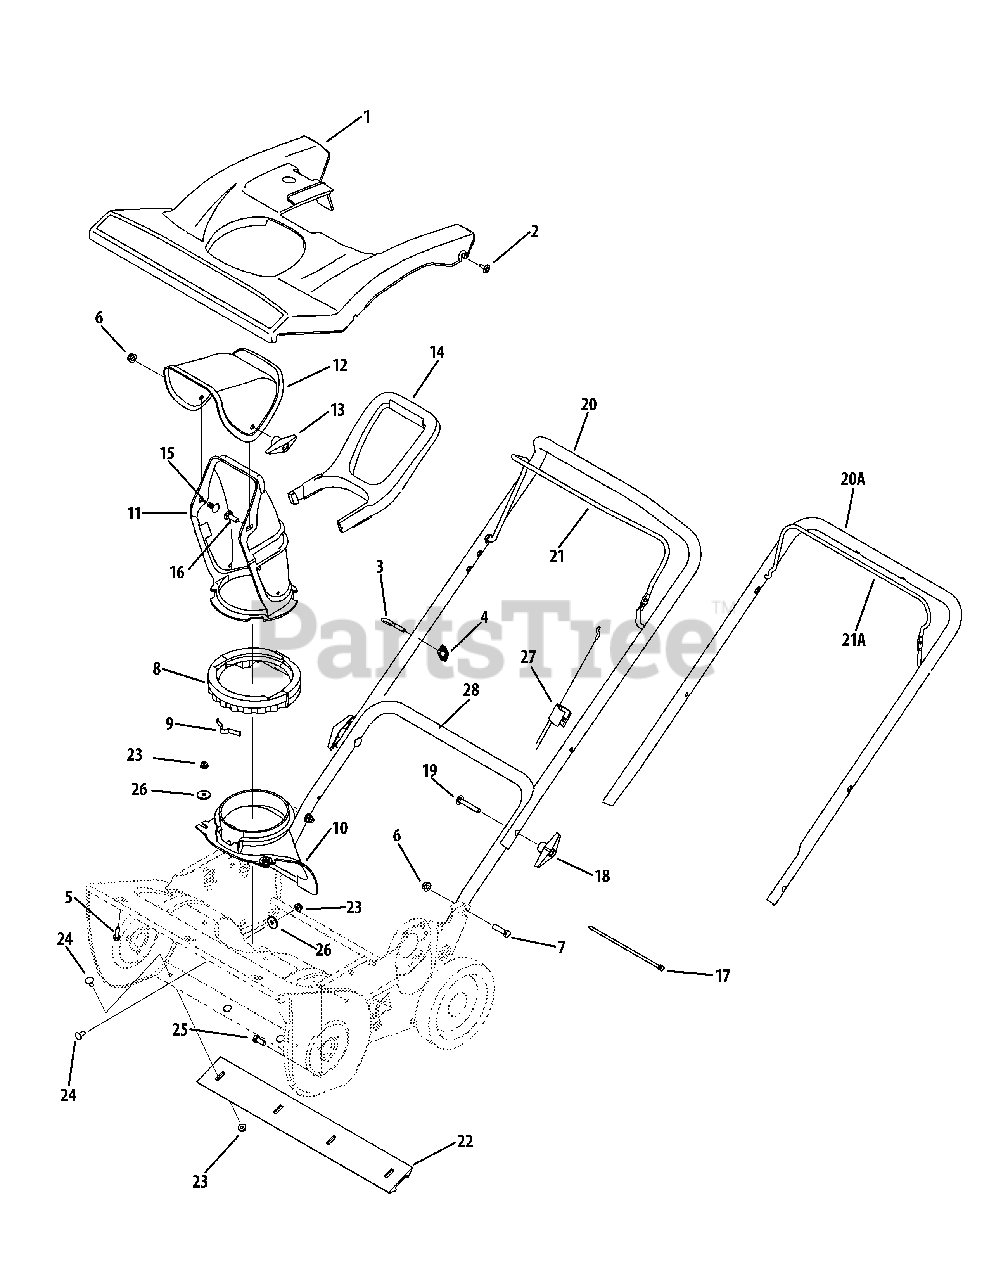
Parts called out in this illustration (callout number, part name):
1	Shroud
2	Hex Washer Screw, 10-16 x .625
3	Eye Bolt, 1.4-20
4	Knob Handle
5	Hex Washer Screw, 1.4-15 x .750
6	Flange Lock Nut, 5.16-18
7	Hex Screw, 5.16-18 x 1.25
8	Lower Chute Ring
9	Chute Adjustment Spring
10	Chute Adapter
11	Lower Chute, 5h Diameter
12	Upper Chute
13	Wing Knob
14	Chute Handle
15	Carriage Bolt, 5.16-18 x .750
16	Carriage Bolt, 5.16-18 x 1.00
17	Cable Tie, 3.16 x .05 x 7.4
18	Wing Nut
19	Carriage Screw, 5.16-18 x 2.00
20	Gullwing Handle
21	Gullwing Control Bail
21A	Control Bail
22	Shave Plate, 21h
23	Flange Lock Nut, 1.4-20
24	Carriage Screw, 1.4-20 x .62
25	Hex Screw, 5.16-18 x .75
26	Flat Washer, .265 x .938 x .120
27	Clutch Cable
28	Lower Handle
